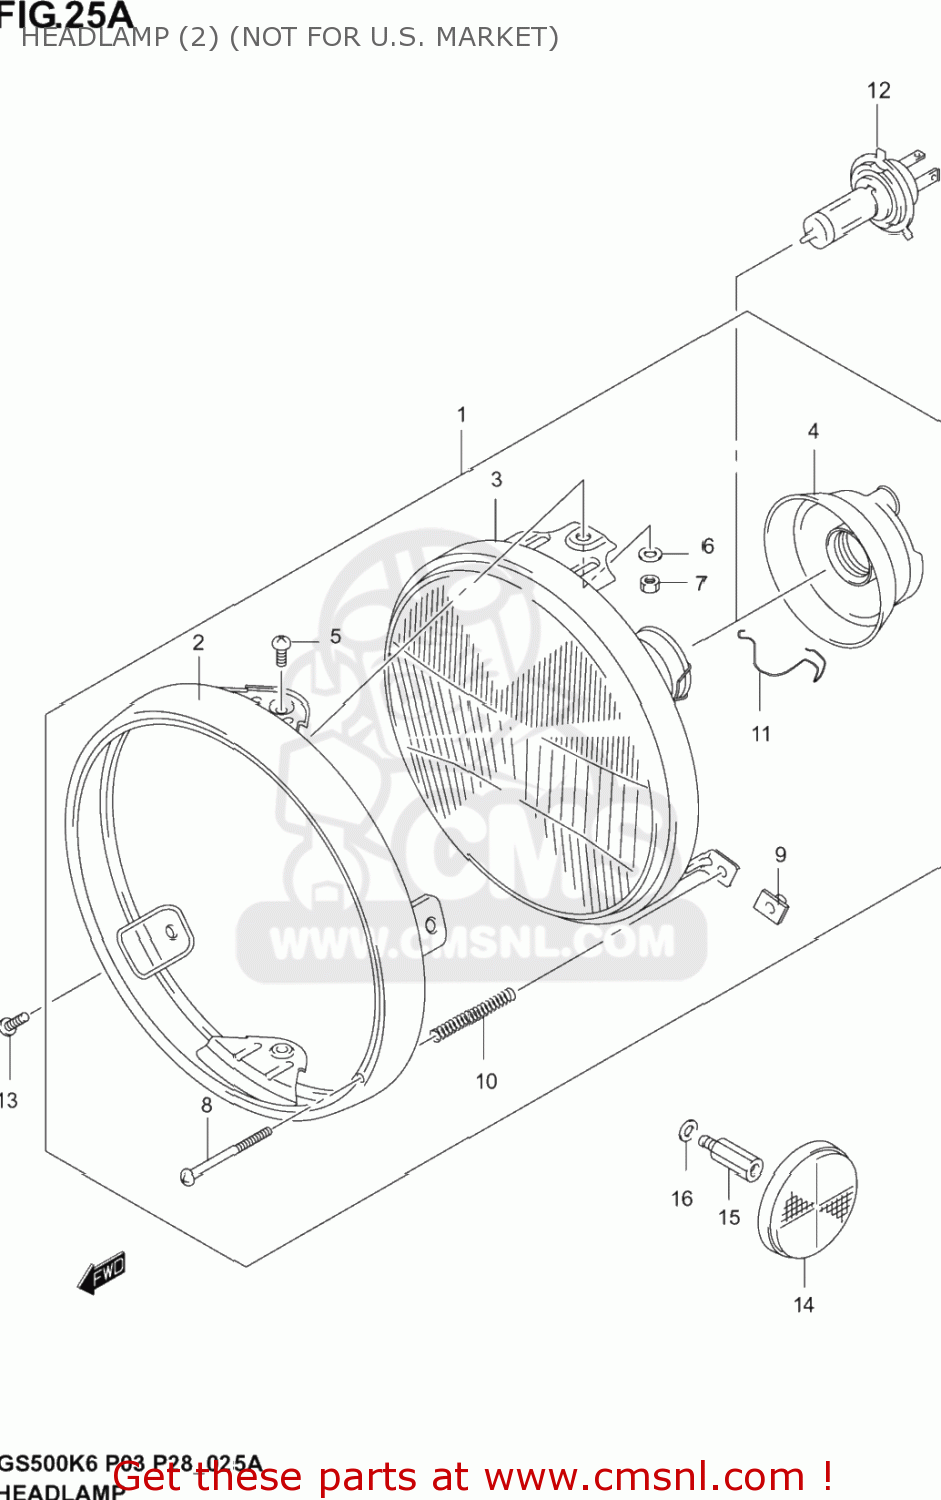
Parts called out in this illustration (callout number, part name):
1	HEADLAMP ASSY
2	RIM
3	LAMP UNIT
4	COVER, SOCKET
5	SCREW
6	WASHER
7	NUT
8	SCREW,ADJUSTIN
9	NUT
10	SPRING
11	SPRING
12	BULB(12V60/55W,H4)
13	BOLT
14	REFLECTOR,REFLEX FR
15	BOLT(5X10)
16	WASHER
